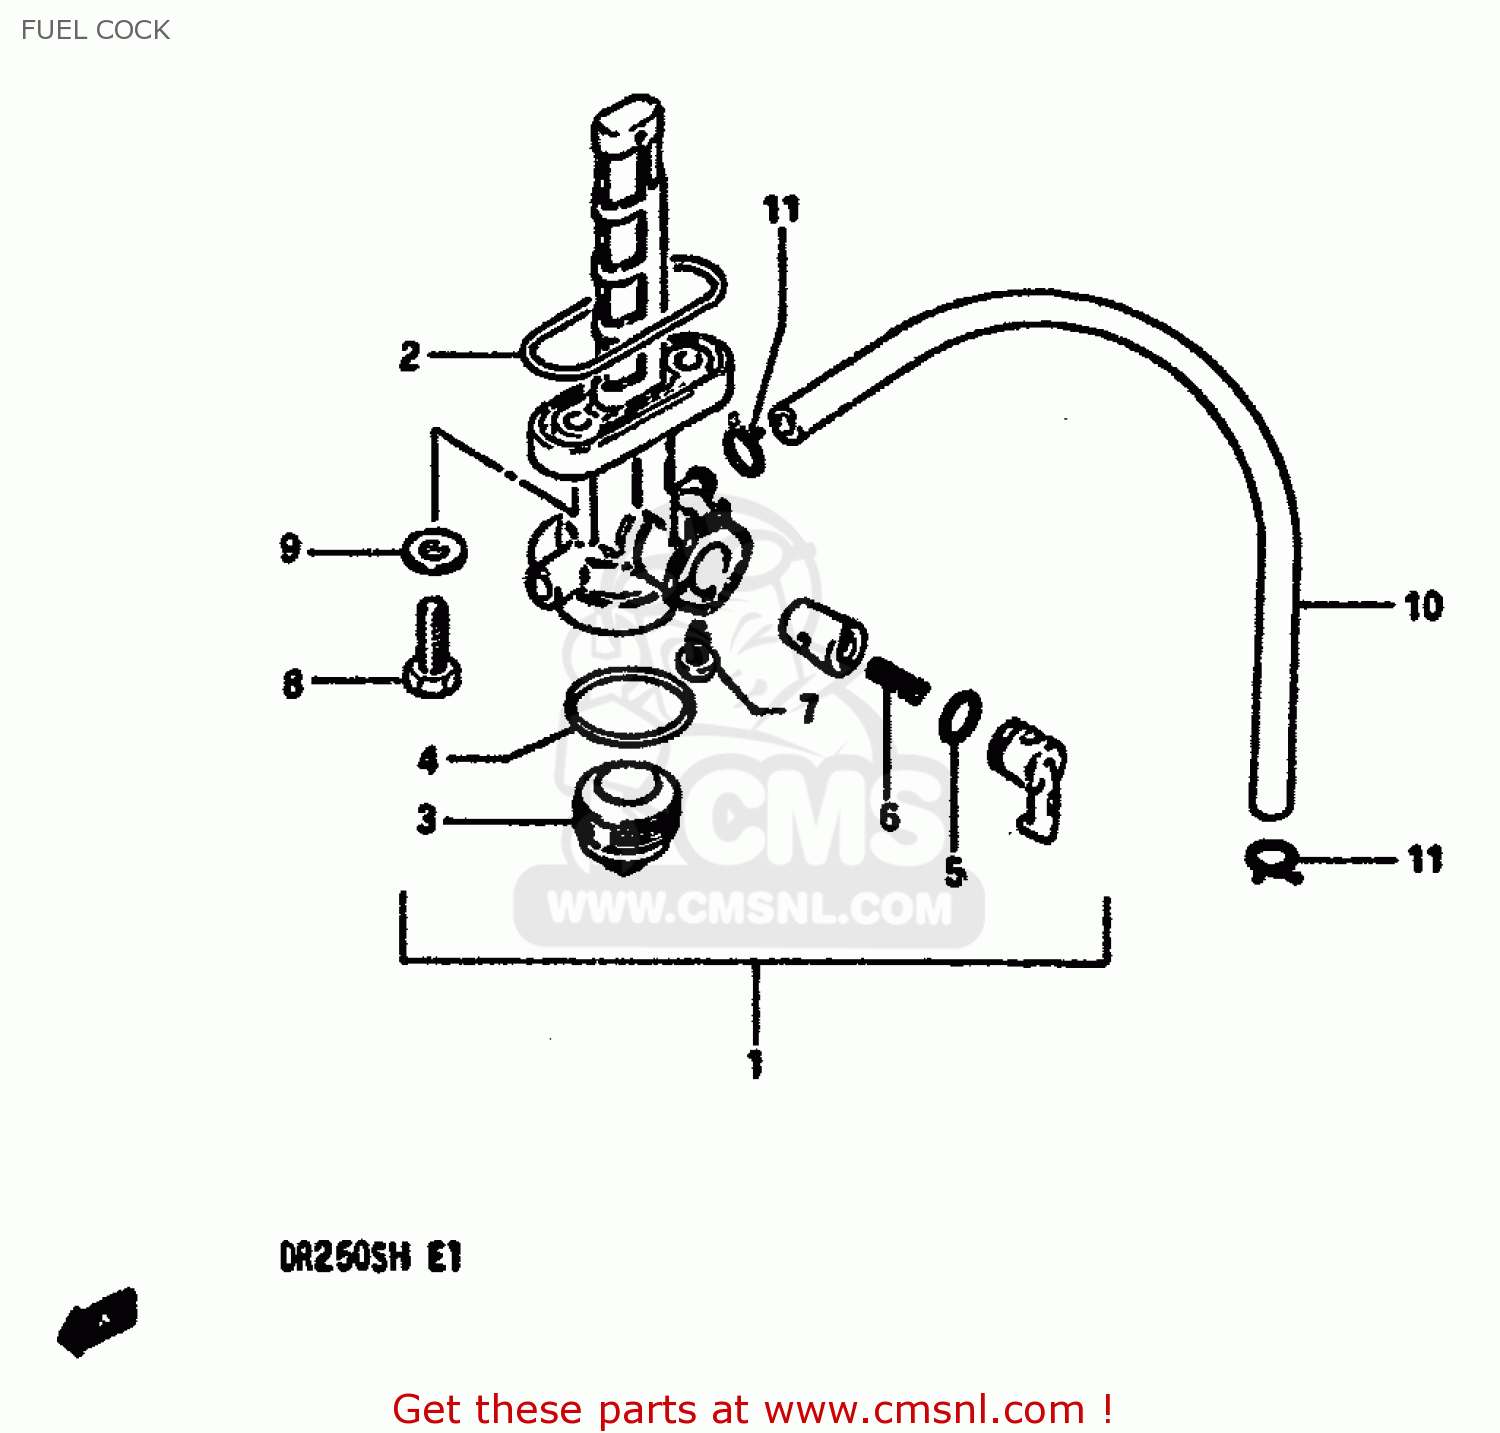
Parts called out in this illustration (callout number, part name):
1	COCK ASSEMBLY,FUEL
2	O RING,FUEL COCK
3	CUP,STRAINER
4	GASKET,FILTER (NAS)
5	O-RING
6	SPRING
7	SCREW
8	BOLT
9	GASKET(6.2X13X1.2) (NAS)
10	HOSE
11	CLIP
